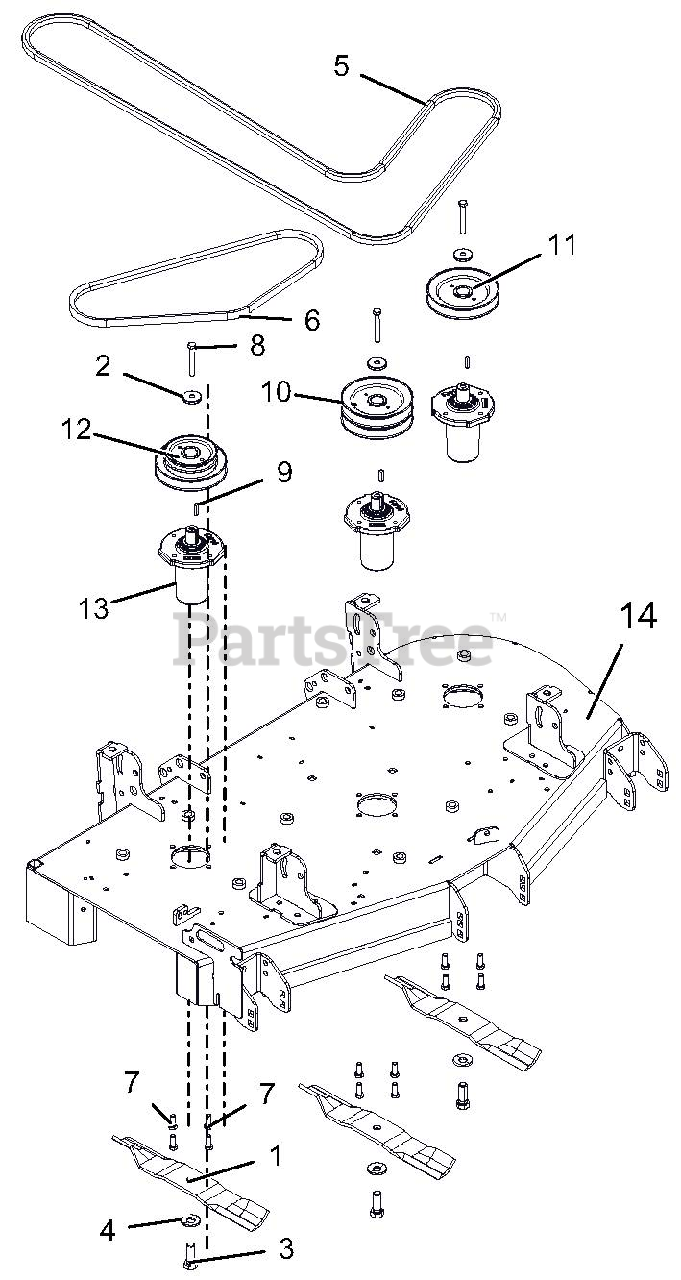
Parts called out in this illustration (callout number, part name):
1	BLADE, MULCH 16.25
2	RETAINER, SHEAVE SPINDLE
3	BLT, HEX .62-18X1.75 GR8 YWZC
4	WSHR, BLVL .63X1.625X.14
5	BELT, BB 118.00 WRAPPED HEX
6	V-BELT, B-RAW EDGE COGGED
7	BLT-HEX .38-16X1.00 GR5 YWZC EP30
8	BLT-HEX .38-16X2.75 GR8 YWZC
9	KEY-SQ .250X.250X1.00 RC 40-50
10	PULLEY, DOUBLE-1" ID X 5.75" OD-BLACK
11	PULLEY, V - 1" ID X 5.75" OD-BLACK
12	PULLEY, DOUBLE -1" ID X 5.75" & 4.25" OD
13	SERVICE, ASM SPINDLE- DUCTILE
14	WLDMT, 48'' PT100 SIDE DISCH DECK
